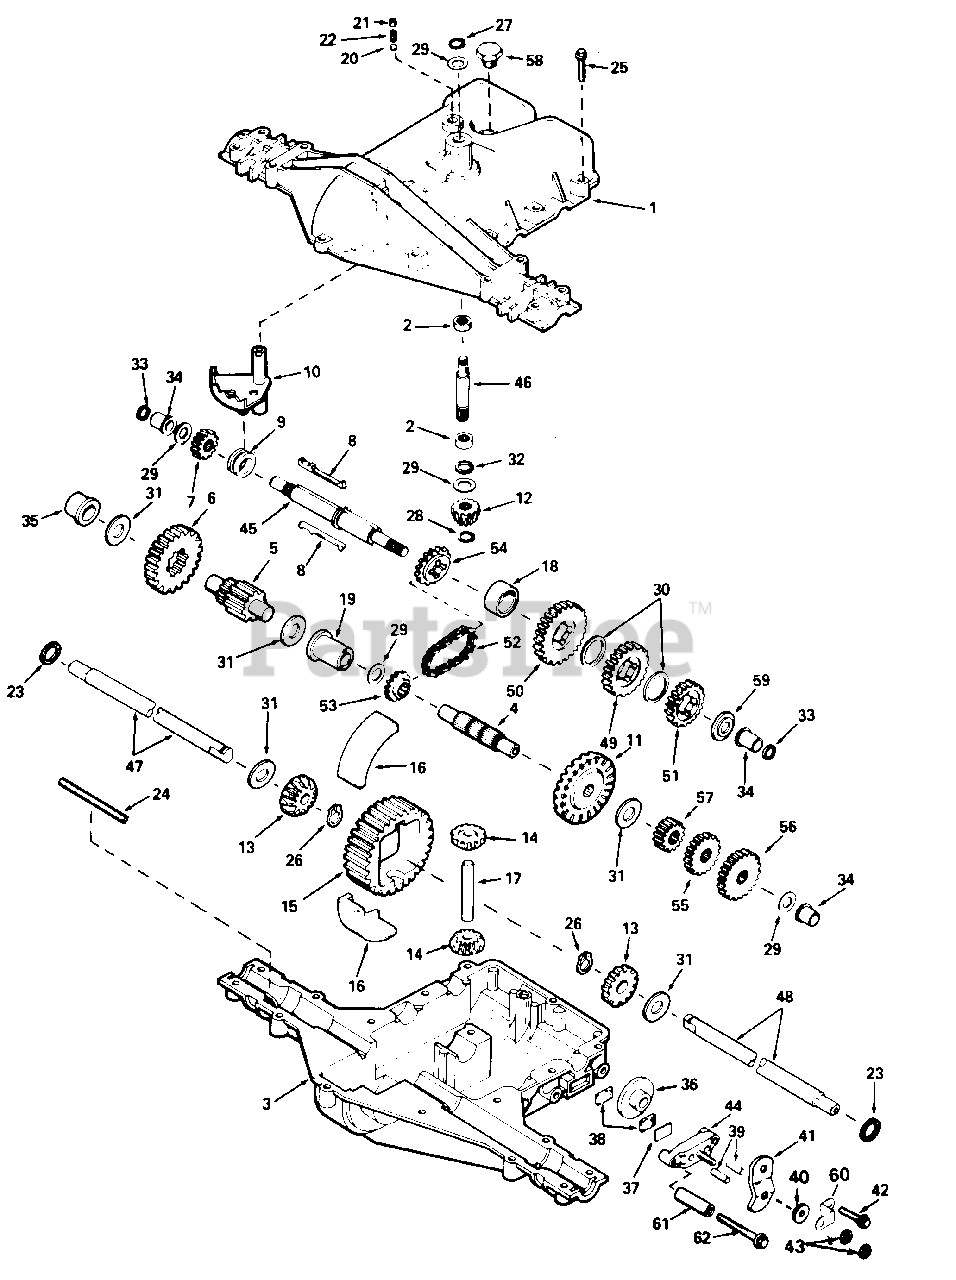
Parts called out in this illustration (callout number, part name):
1	Cover, Transaxle
2	Bearing, Needle
3	Case, Transaxle
4	Shaft, Counter
5	Shaft & Pinion Ass'y., Output
6	Gear, Output
7	Gear, Spur (15 Teeth)
9	Collar, Shifter
10	Rod & Fork Ass'y., Shift
11	Gear, Bevel (42 Teeth)
12	Bevel Pinion, Input
13	Gear, Bevel
14	Gear, Bevel Pinion
15	Gear, Ring
16	Block, Bearing
17	Pin, Drive
18	Spacer
19	Bushing, Flanged
20	Ball, Steel (5/16" Dia.)
21	Set Screw, 3/8-16 x 3/8
22	Spring
23	Ring, Felt
24	Packing, Felt
25	Screw, Flanged Hex Hd. Thd. Forming, 1/4-20 x 1-1/4
26	Ring, Retainer
27	Ring, Retainer
28	Ring, Retainer
29	Washer, Thrust
30	Washer, Thrust
31	Washer
32	"O" Ring
33	Seal, Square Cut
34	Bushing, Flanged
35	Bushing, Flanged
36	Disk, Brake
37	Plate, Brake Pad
38	Pad, Brake
39	Pin, Dowel
40	Washer, Flat
41	Lever, Brake
42	Screw, Flanged Hex Hd. Thd. Forming, 1/4-20 x 1-1/4
43	Nut, Lock, 5/16-24
44	Holder, Brake Pad
45	Shaft, Brake
46	Shaft, Input
47	Axle (12-1/2" Lg.)
48	Axle (15-3/8" Lg.)
49	Gear, Spur (25 Teeth)
50	Gear, Spur (35 Teeth)
51	Gear, Spur (20 Teeth)
52	Chain, Roller (No. 41 Chain, 24 Links)
53	Sprocket (9 Teeth)
54	Sprocket (18 Teeth)
55	Gear, Spur (25 Teeth)
56	Gear, Spur (30 Teeth)
57	Gear, Spur (15 Teeth)
58	Plug, Hex Hd., 9/16-18 Thd.
59	Washer, Thrust
60	Bracket
61	Spacer
62	Screw, Flanged Hex Hd. Thd. Forming, 1/4-20 x 2-1/4
